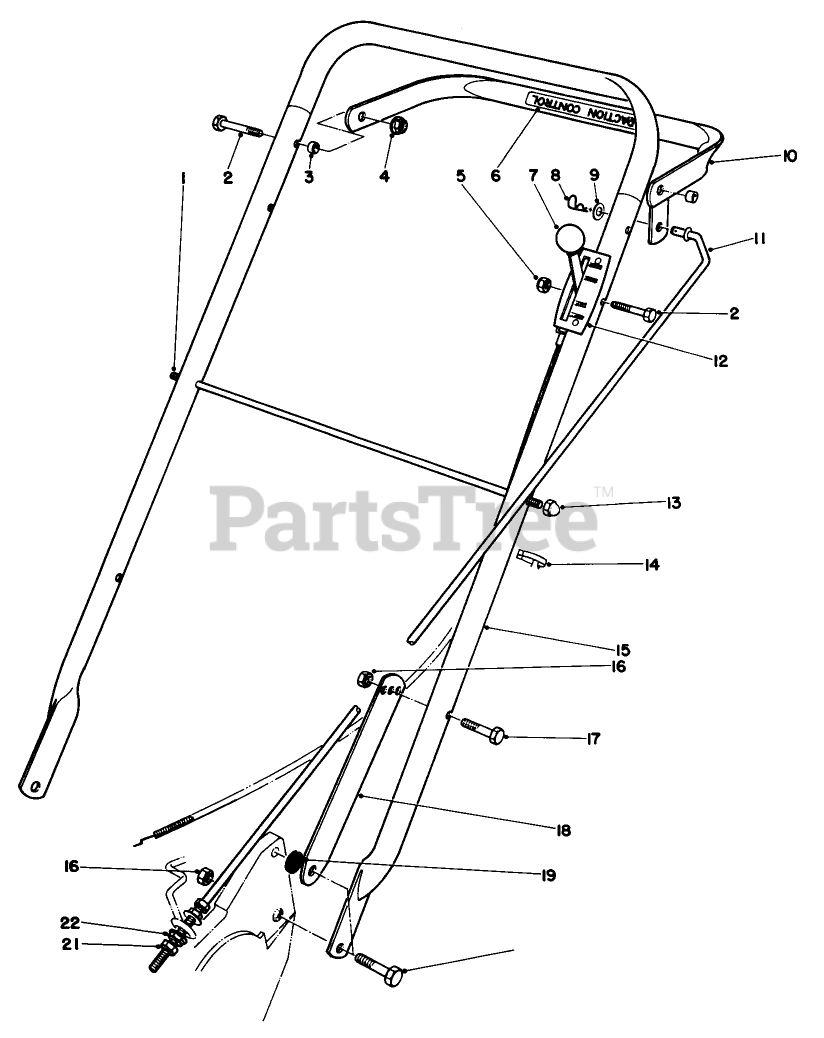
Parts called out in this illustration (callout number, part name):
1	ROD-SUPPORT, BAG
2	SCREW-HH
4	NUT-LOCK, HHF
5	NUT-LOCK, NI
7	KNOB-CONTROL
9	WASHER-PLAIN
10	CONTROL BAIL ASM
13	NUT-CAP
16	NUT-LOCK, NI
17	SCREW-HH
19	HANDLE LATCH SPACER
20	SCREW-SHOULDER
21	NUT-JAM
22	NUT-FLANGE
